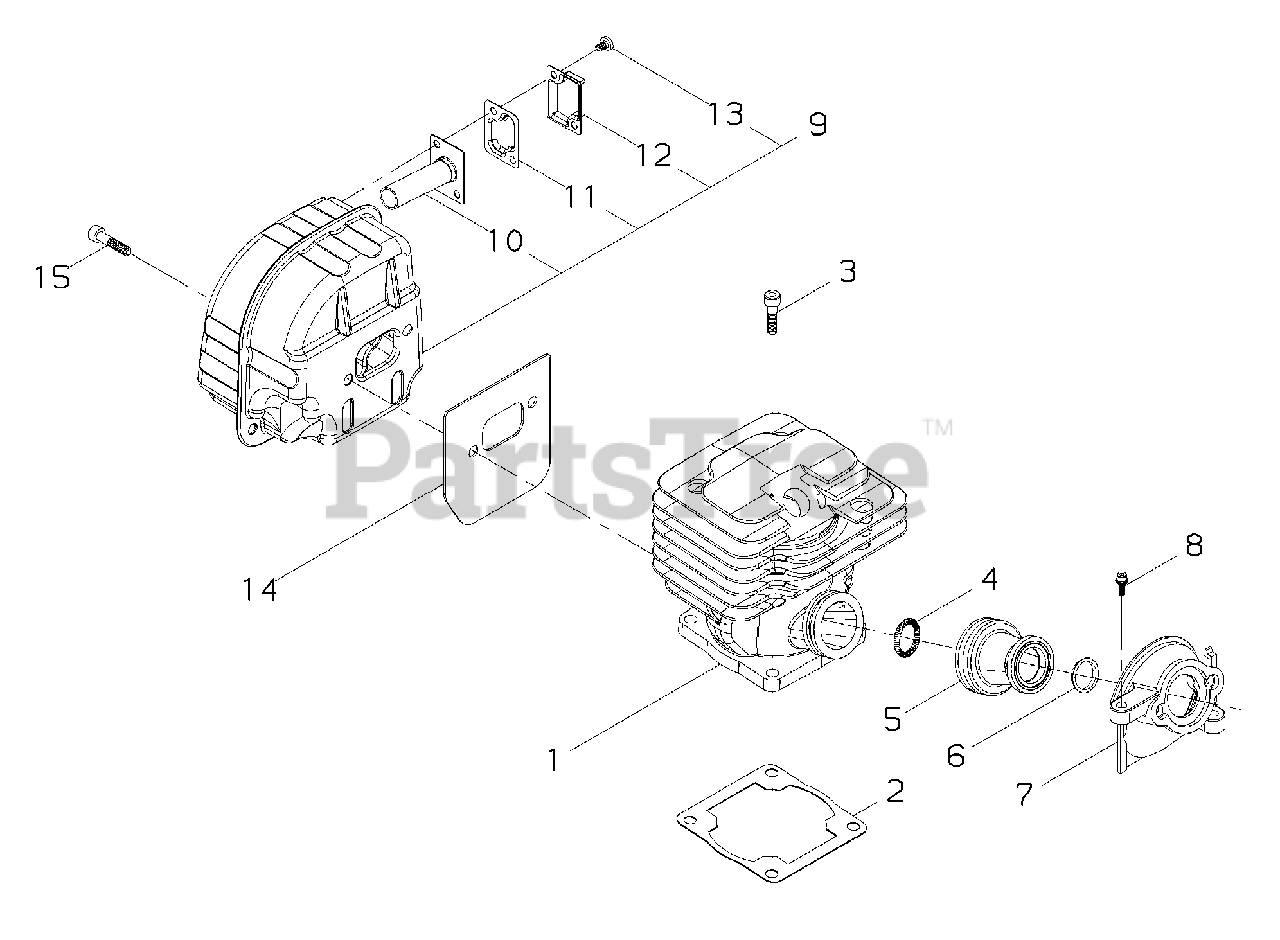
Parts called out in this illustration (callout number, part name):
1	CYLINDER
2	GASKET, CYLINDER
3	BOLT M5×18
4	SPRING
5	BELLOWS, INTAKE
6	COLLAR 16
7	ADAPTOR, INTAKE
8	BOLT M4×16
9	MUFFLER ASSY
10	PIPE, EXHAUST
11	SCREEN, SPARK ARRESTER
12	COVER, SPARK ARRESTER
13	SCREW M4×6
14	HEAT SHIELD, EXHAUST
15	BOLT M5×18
